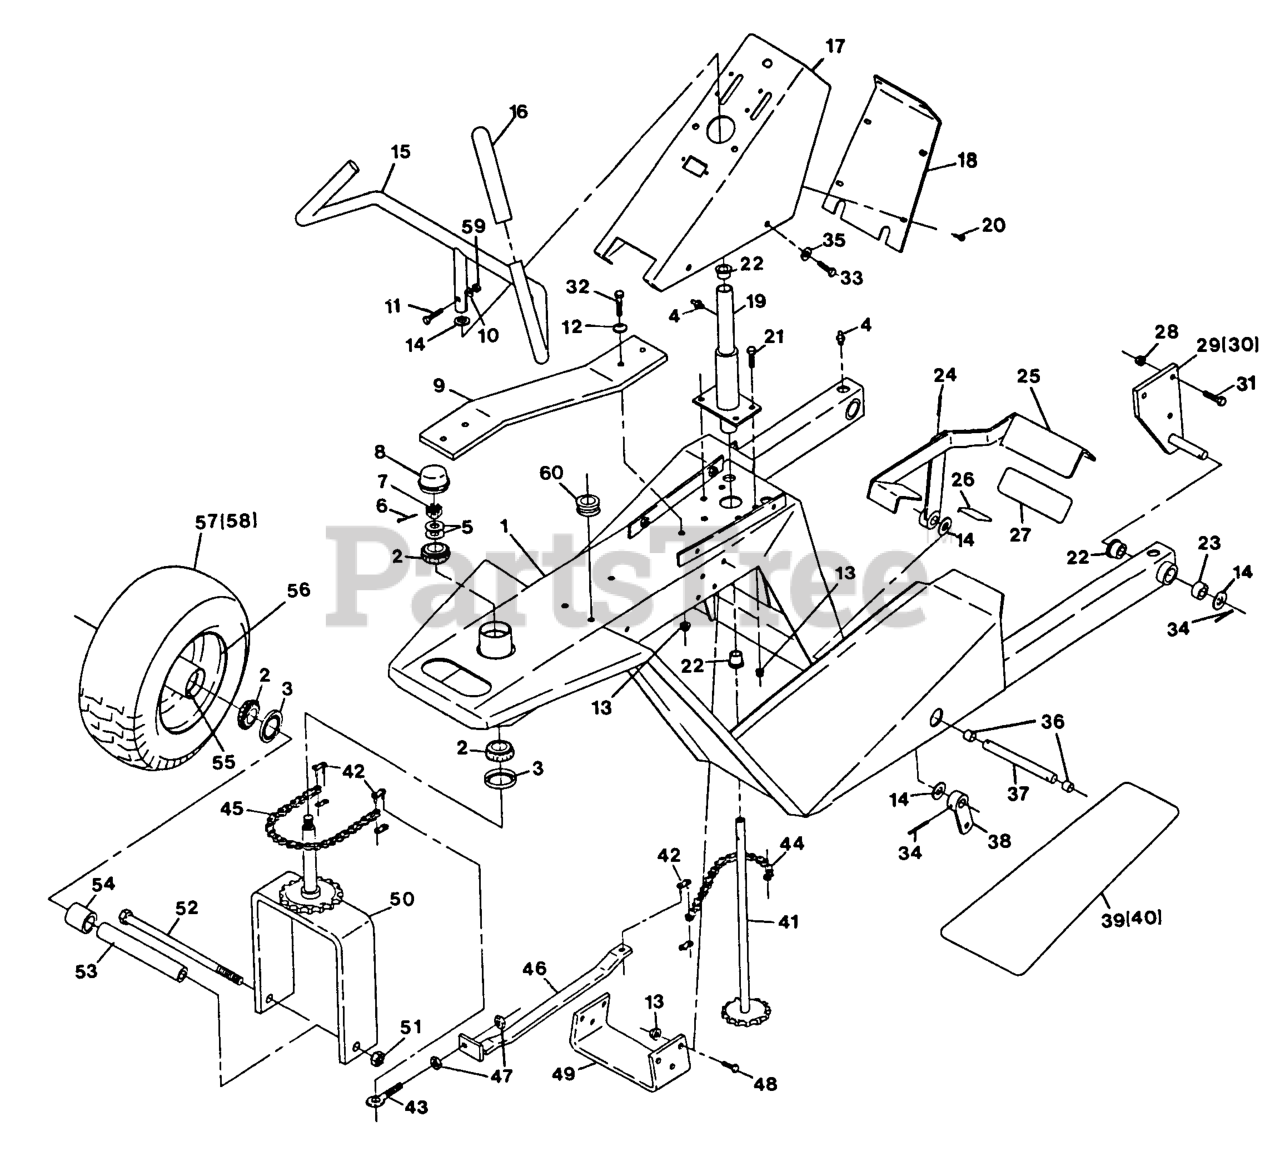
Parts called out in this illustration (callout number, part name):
2	Cone-Bearing Tapered Roller
3	SEAL-GREASE
8	CAP-GREASE
23	SLEEVE,BEARING
24	PIN,ROLL
27	PAD,ANTISKID
29	WLD,BRACKET PIVOT RH
38	WLD,FOOT PEDAL LEVER
39	PAD,ANTISKID RH
43	EYEBOLT, RH
49	STOP,ACTUATOR
52	SCRW,CAP HH
53	BUSHING, WHEEL - PLT
54	SPACER,WHEEL SHORT
55	CUP-BEARING
56	WHEEL 8.00 W/HUB
57	ASM,WHEEL & TIRE
58	TIRE ONLY 8NHS
60	GROMMET
